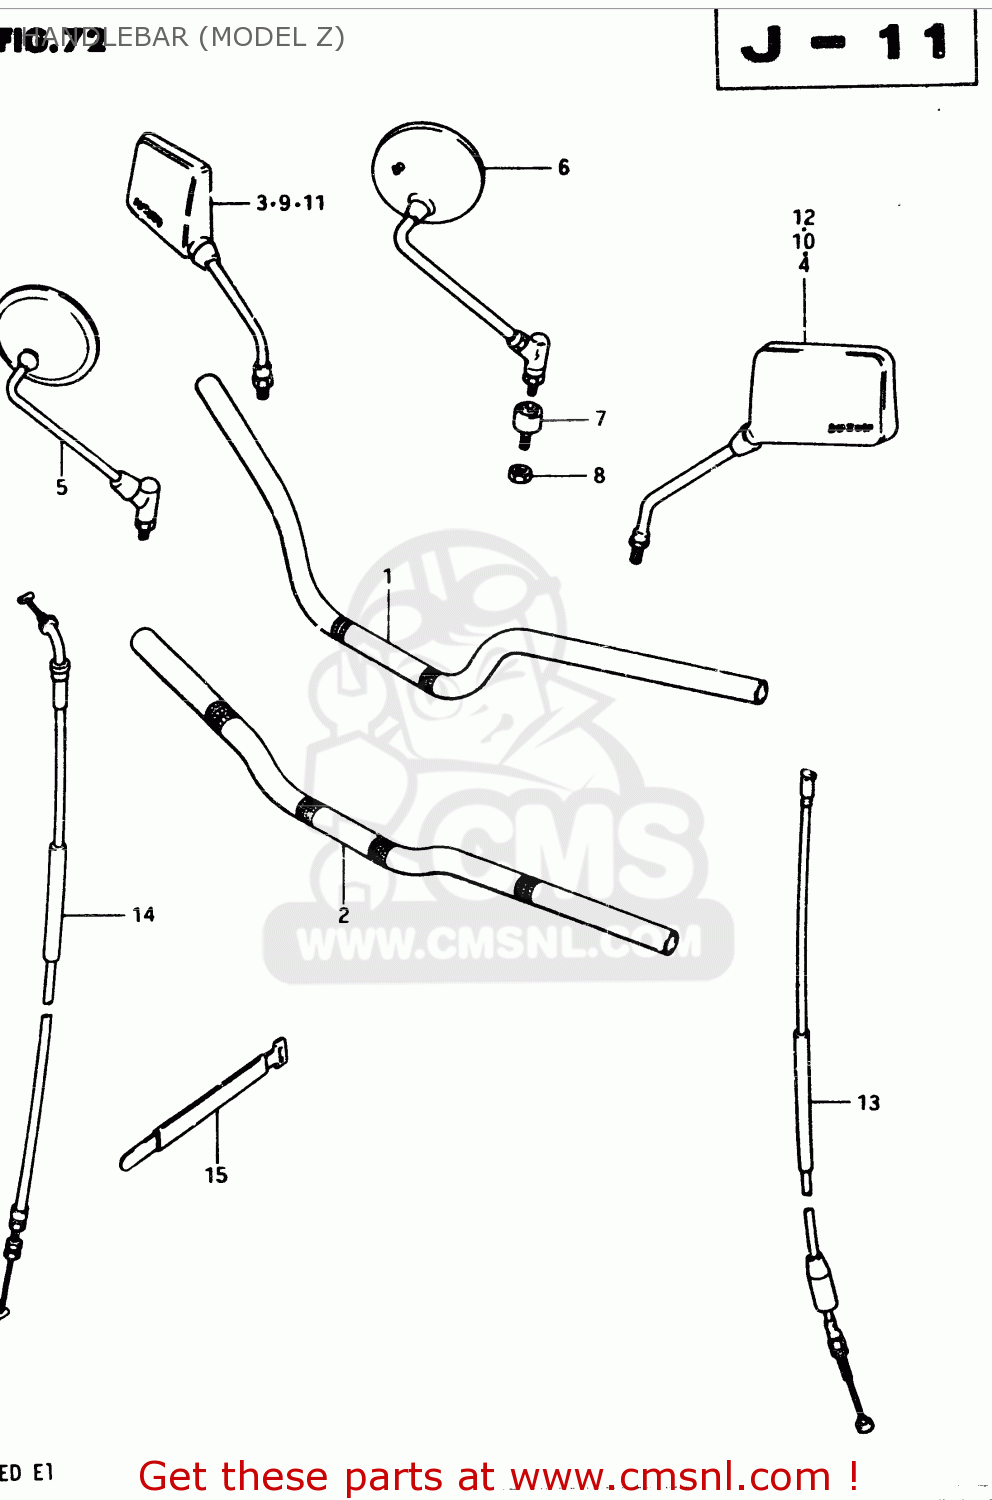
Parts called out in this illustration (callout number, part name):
1	HANDLEBAR (NEUTRAL)
2	HANDLEBAR
3	MIRROR ASSEMBLY,REAR VIEW
4	MIRROR ASSEMBLY,REAR VIEW
5	MIRROR ASSY,RH
6	MIRROR ASSY,RH
7	CUSHION,REAR VIEW MIRROR
8	NUT
9	MIRROR, REAR VIEW RH
10	MIRROR, REAR VIEW LH
11	MIRROR, REAR VIEW RH
12	MIRROR, REAR VIEW LH
13	CABLE ASSY,CLUTCH
14	CABLE ASSEMBLY,THROTTLE
15	CLAMP
